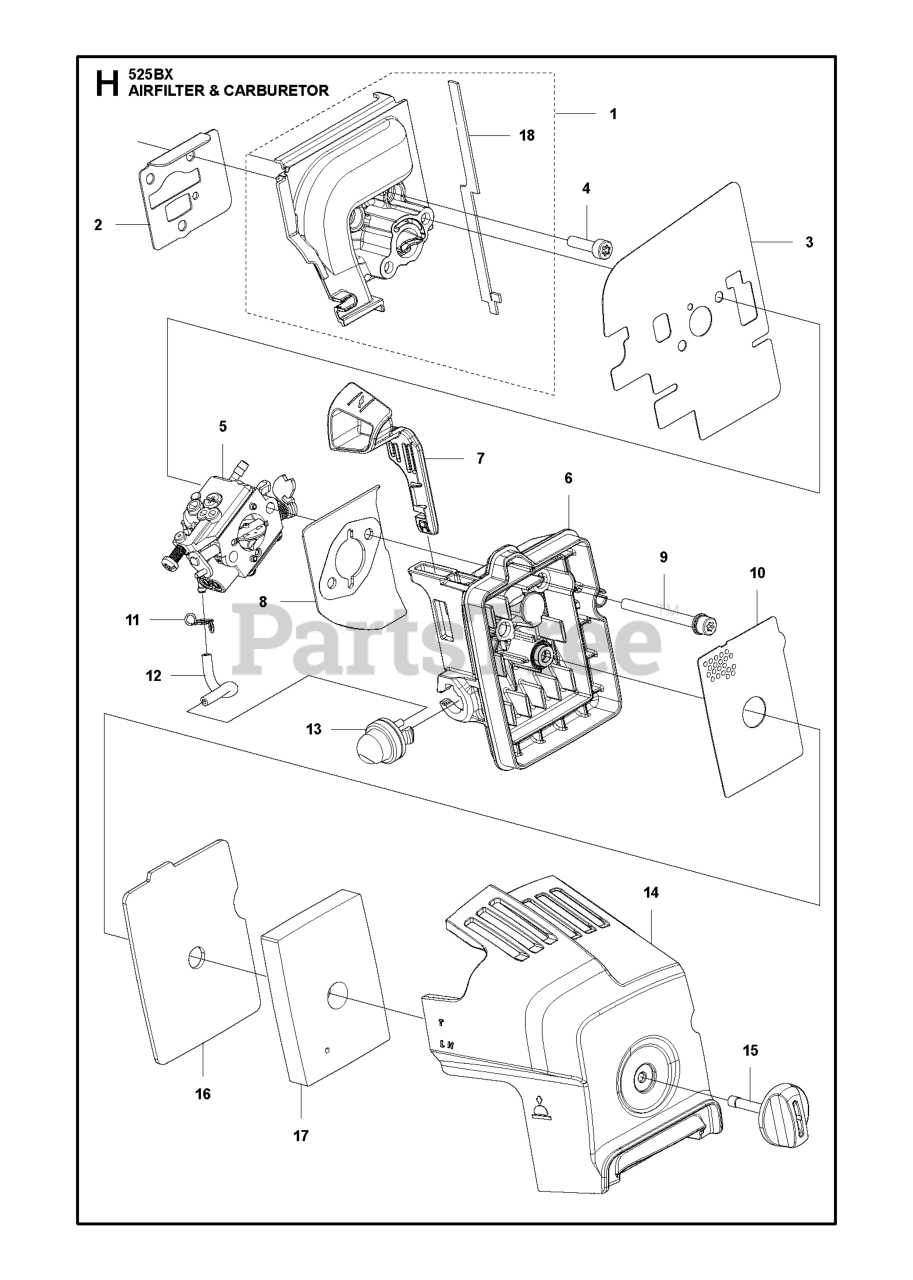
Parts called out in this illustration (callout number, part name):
1	INSULATOR ASSY
2	GASKET INSULATOR
3	GASKET CARBURETOR
4	BOLT M5X0.8 L20 WITH THREAD L
5	CARBURETTOR ASSY
5	CARBURETTOR ASSY H226D-03-0000
6	FILTER HOUSING
7	CHOKE CONTROL
8	GASKET CLEANER
11	CLAMP FUEL LINE
12	FUEL HOSE 65
13	AIR PURGE BUBBLE
14	FILTER COVER GRAY
15	KNOB CLEANER COLOR: GREY
16	AIR FILTER FELT
17	AIR FILTER URETHANE
18	INSULATING SHEET
